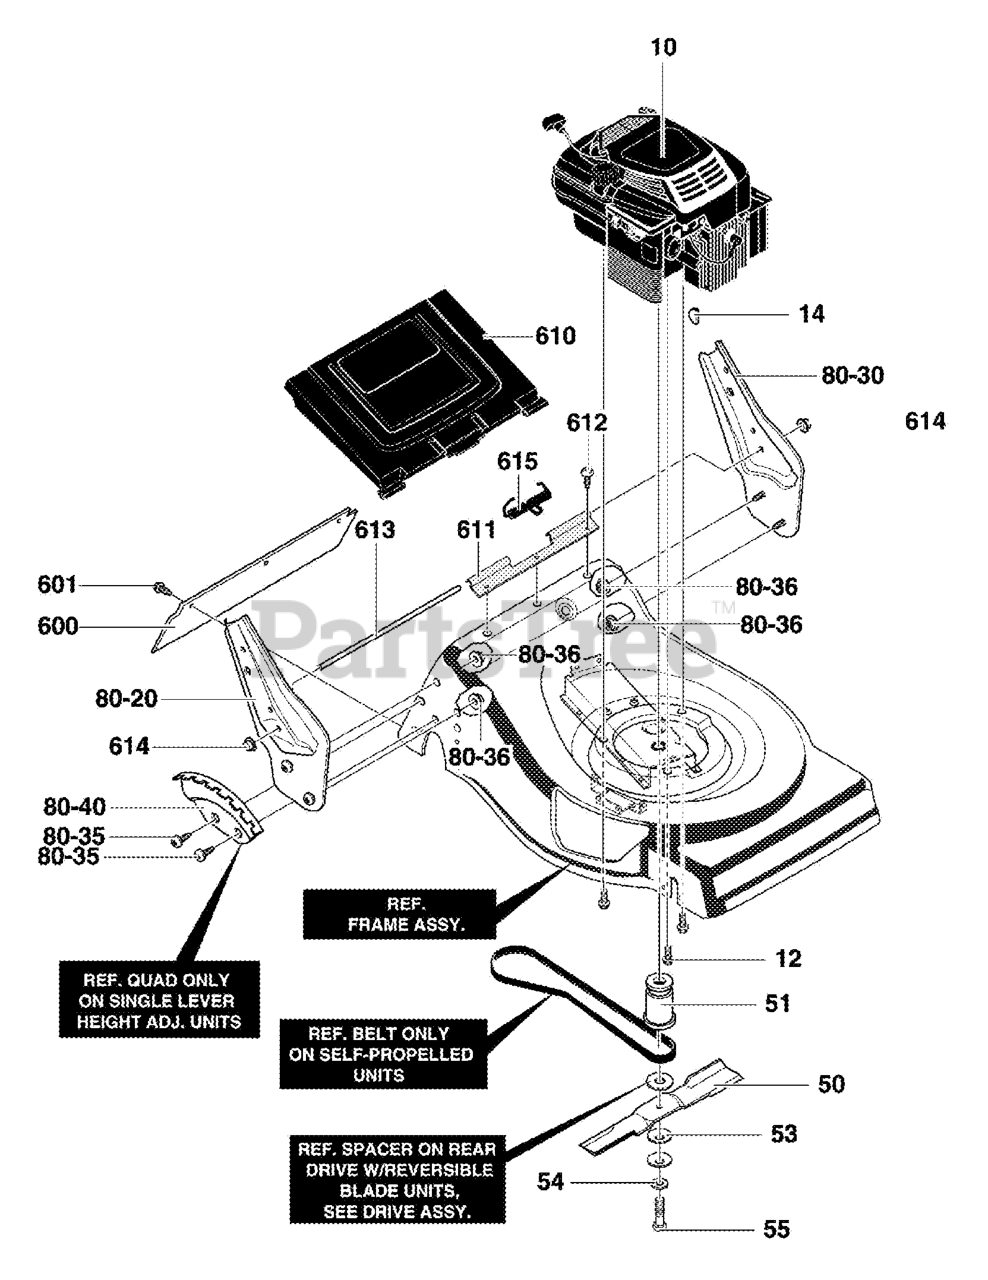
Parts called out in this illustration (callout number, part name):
10	Engine
14	Key, Woodruff
51	Adapter, Blade
53	Washer
54	Flatwasher
80-20	Bracket, Handle - RH
80-30	Bracket, Handle - LH
80-36	Nut, 5/1-618
80-40	Quadrant
600	Deflector, Rear
601	Screw, 10-16x.50
610	Door, Rear
611	Spacer, RR Door
612	Screw, 10-16x.50
613	Rod, Pivot
614	Cap, Push On
615	Spring, Torsion
